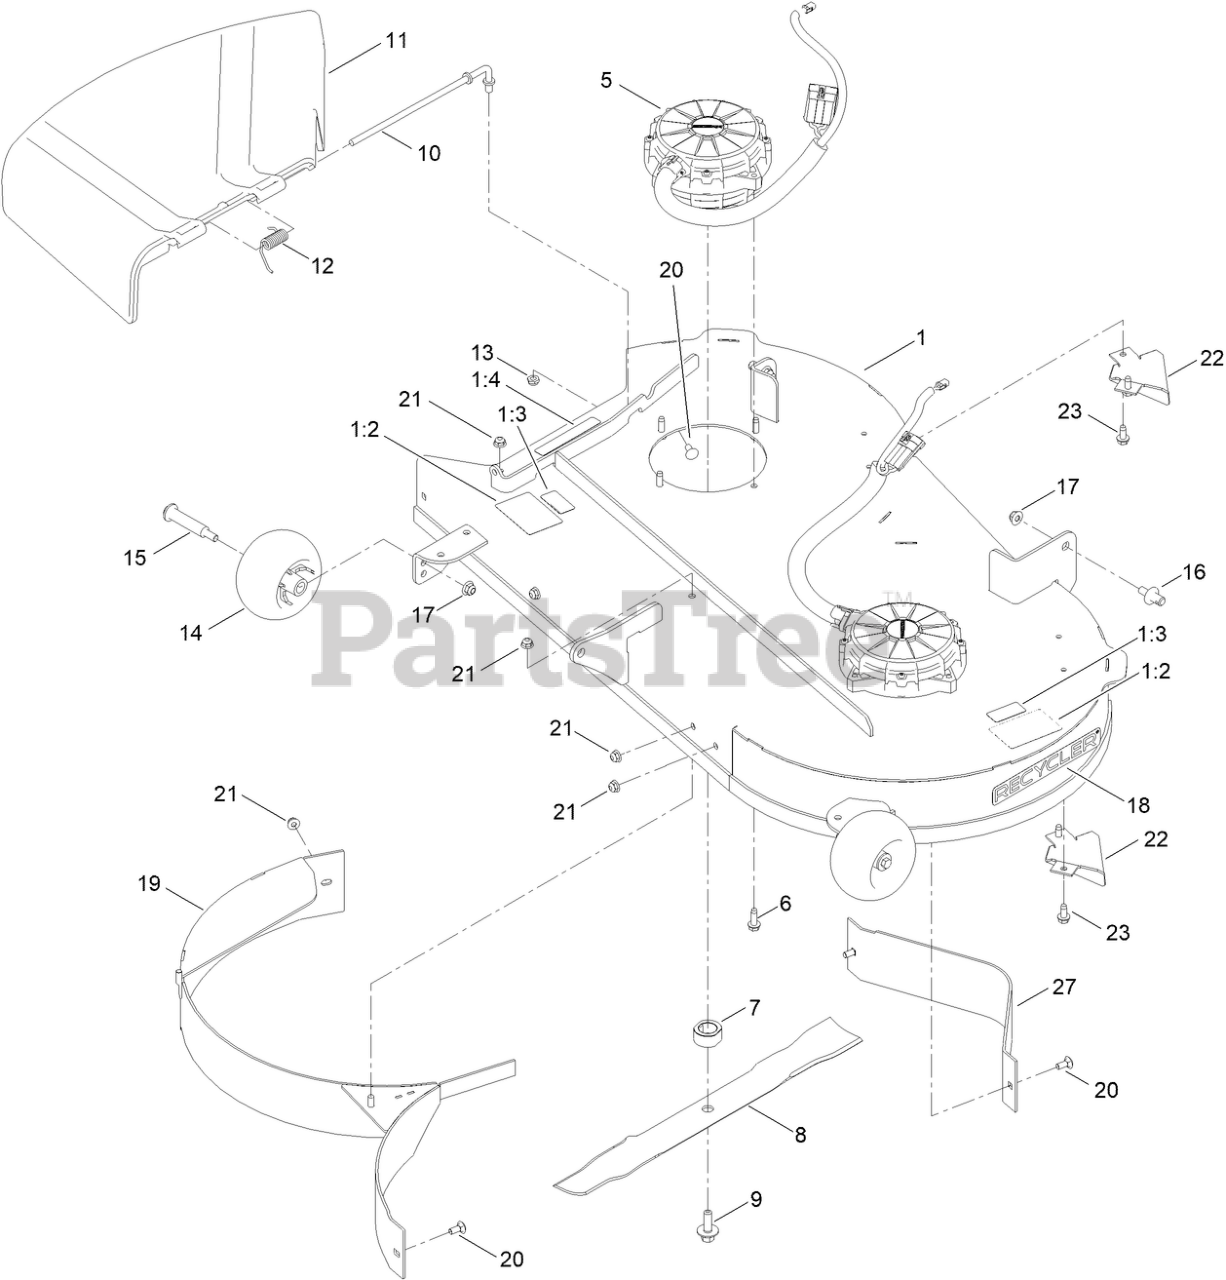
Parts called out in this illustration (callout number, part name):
1	42 IN DECK AND DECAL ASM
1:2	DECAL-DANGER, DECK
1:3	DECAL-NO SPRAY
1:4	DECAL-DANGER
5	MOTOR-DECK
6	SCREW-THD ROLL, HWH
7	DRIVER-BLADE
9	BOLT-BLADE, SEMS
10	ROD-PIVOT
11	DEFLECTOR-DISCHARGE
12	SPRING-TORSION
13	NUT-HEX
14	ROLLER-SCALP, ANTI
15	BOLT-SHOULDER
16	PIN-DECK
17	NUT-HF, NI
19	BAFFLE-RECYCLING [WELDED][BLACK]
20	BOLT-CARR
21	NUT-HF
22	KICKER-FLANGED
23	SCREW-HWHTF
27	DEFLECTOR-42"
